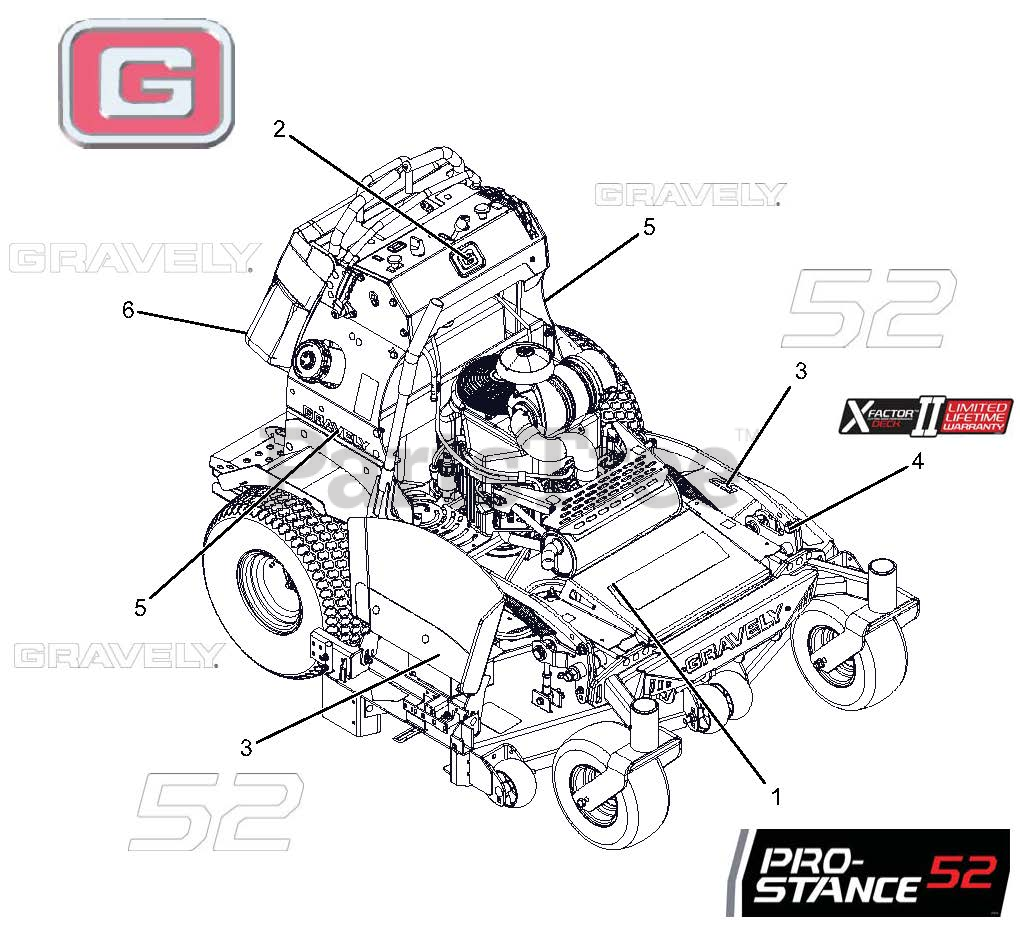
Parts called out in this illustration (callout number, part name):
1	DECAL, PROSTANCE 52
2	DECAL, GRAVELY BRAND
3	DECAL, 52"
4	DECAL, X-FACTOR DECK
5	DECAL, 9.5" GRAVELY LOGO
6	DECAL, 13.5" GRAVELY LOGO
